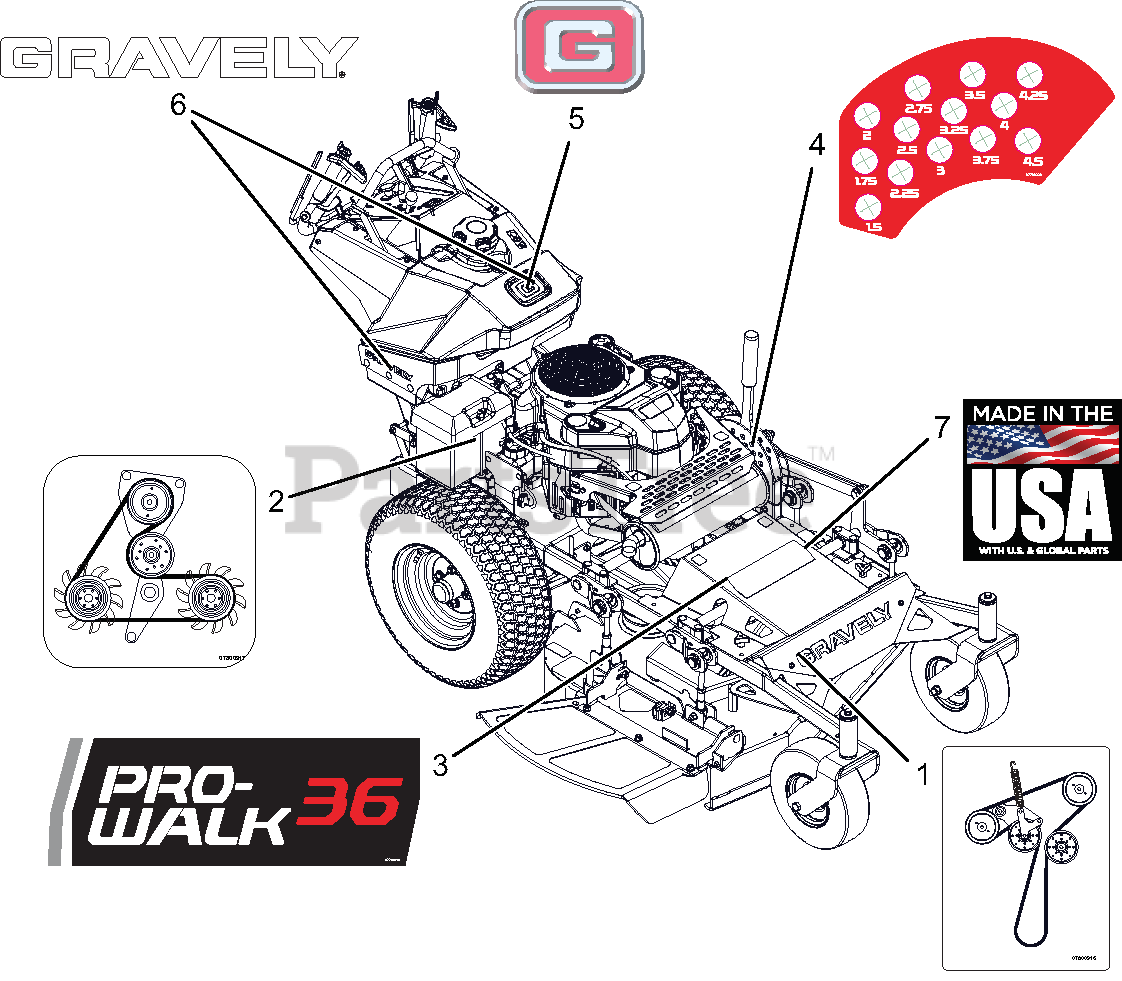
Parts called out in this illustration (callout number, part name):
1	DECAL, 36 PW DECK BELT ROUTING
2	DECAL, 36 PW TRANS BELT ROUTE
3	DECAL, PRO WALK 36"
4	DECAL, 36" HOC
5	DECAL, GRAVELY BRAND
6	DECAL, 6.5" GRAVELY LOGO
7	DECAL, MADE IN USA
